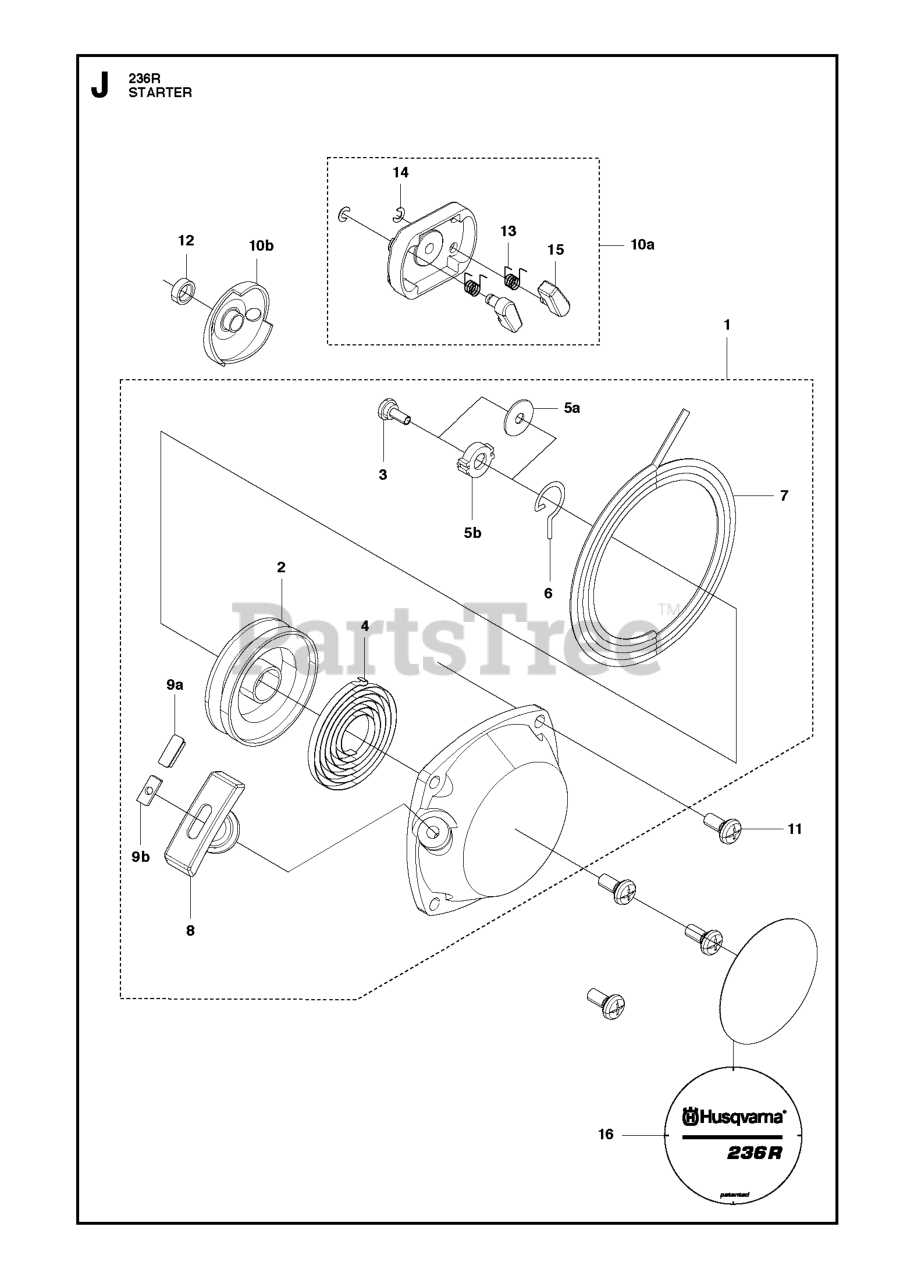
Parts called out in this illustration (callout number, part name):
2	REEL
3	SCREW
4	SPRING
4	SPRING, SPIRAL
6	SWING ARM
8	KNOB
8	STARTER HANDLE
13	SPRING
14	CLIP
15	STARTER RATCHET
